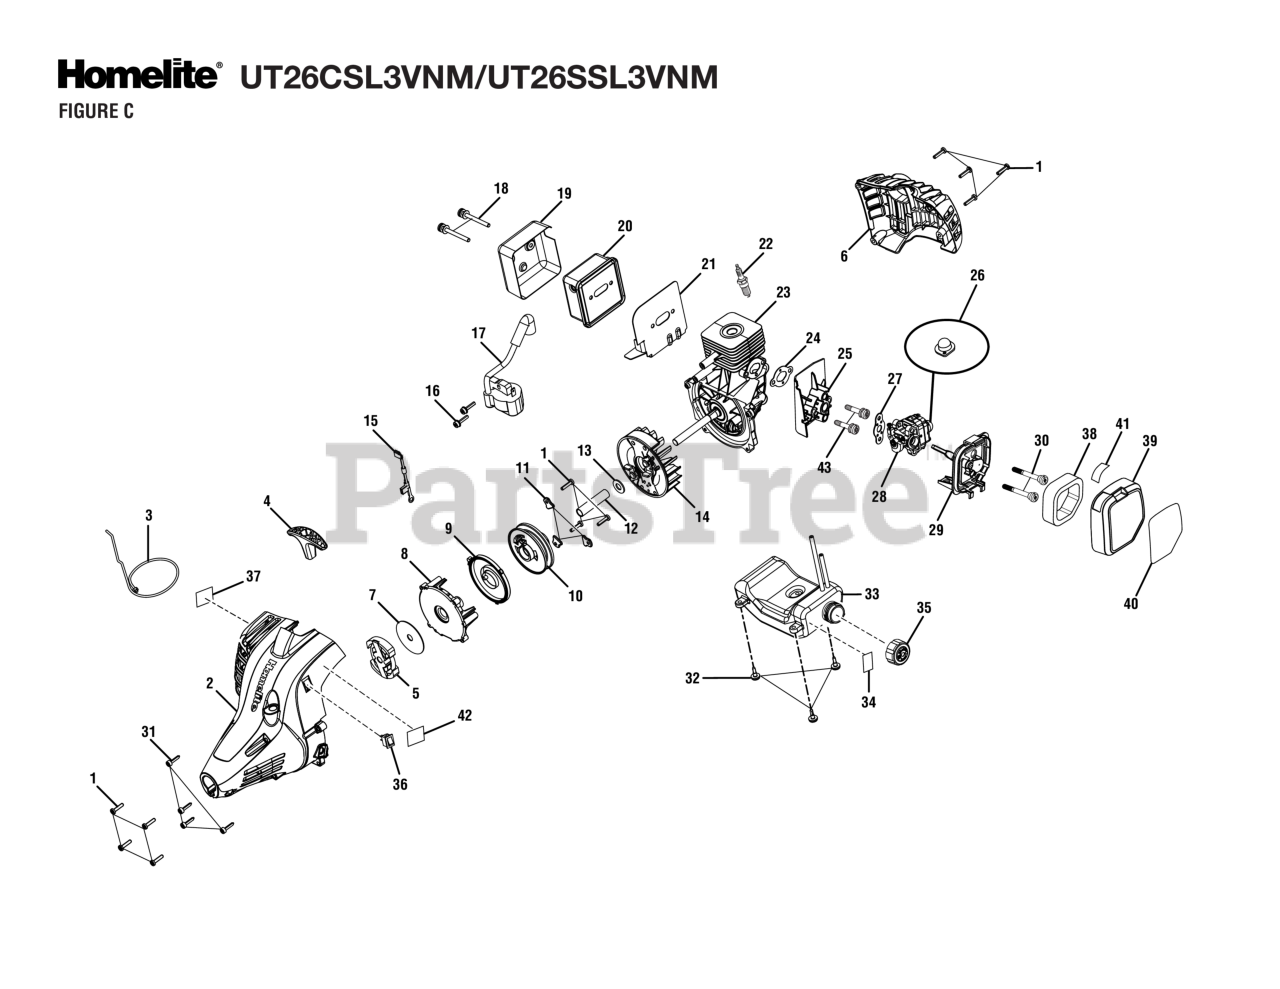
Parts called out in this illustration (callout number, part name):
1	Screw (M4 x 20 mm, T20 Torx Pan Hd. S.T.)
2	Starter Housing Assembly
3	Starter Rope (42 in.)
4	Pulley Handle
5	CLUTCH ASSEMBLY
6	Rear Housing
7	Washer (ID9.63 x OD50.75 x 1.10t)
8	Starter Housing
9	Spring & Container Assembly
10	Starter Pulley Assembly
11	Pulley Retainer
12	Spacer Tube
13	Washer (ID9.75 x OD20 x 1.6t)
14	Flywheel Assembly
15	Lead Assembly
16	Screw w/Washer (M4 x 19 mm, T20 Torx Pan Hd. S.T.)
17	Ignition Module
18	Screw w/Washers (10-24 x 2-1/8 in., T25 Torx Truss Hd.)
19	Muffler Housing
20	Muffler Assembly
21	Muffler Gasket
22	SPARK PLUG CHAMPION - RCJ-6Y
23	Short Block Assembly
24	Inner Heat Dam Gasket
25	Heat Dam Deflector
28	Carburetor Assembly
29	Airbox Base Assembly
30	Screw (M5 x 45 mm, T20 Torx Truss Hd.)
31	Screw w/Washer (M4 x 16 mm, T25 Torx Truss Hd.)
32	Shoulder Screw w/Washer (M4 x 14 mm, T25 Torx Truss Hd.)
33	Fuel Tank w/Label & Cap Assembly
34	Fuel Tank Warning Label
35	Fuel Cap Assembly
36	Stop Switch (Momentary Contact)
37	Warning Label (Combustion)
38	Air Filter (Element)
39	Air Box Cover
40	Starting Label
41	Choke Label
42	Primer Bulb Location Label
43	Screw w/Washers (M5 x 30 mm, T25 Torx Pan Hd.)
